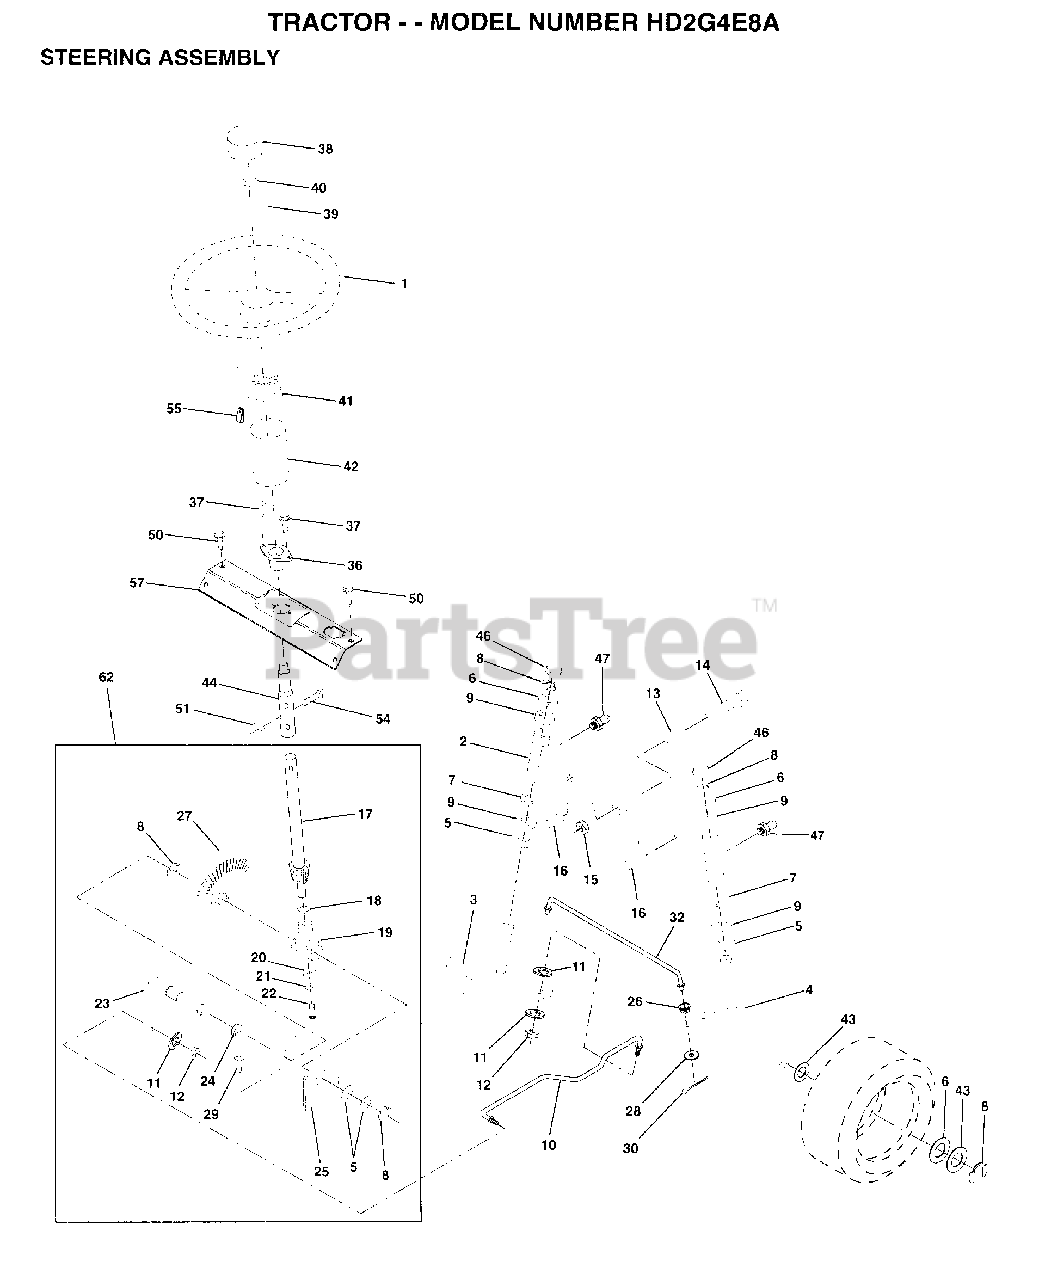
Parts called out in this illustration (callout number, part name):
1	WHEEL STR AYP BLK
2	AXLE ASM FRONT
3	SPINDLE LH
4	SPINDLE RH
5	WASHER .T
6	WASHER
7	WASHER
8	RING
9	COL. SRTG. BEAR.
11	LOCKWASHER
13	BEARING
14	BOLT HEX 5/8-11
15	"NUT-LOC,FLANGE LT"
16	AXLE PIN
17	SHAFT ASM STEERIN
18	THRUST WASHER
19	SUPPORT.SHAFT
21	LOCKWASHER
22	SCREW.SCKTHD.CAP
24	NYLINER T
25	"BRKT,STEERING"
26	BUSHING.DRAGLINK
27	GEAR SECTOR
28	WASHER
29	SCREW
30	COTTER PIN
32	TIE ROD
38	CAP STEER AYP
39	WASHER T
40	GRIPCO NUT
41	ADAPTER-WHEEL LT
42	BOOT SHAFT STEER
43	WASHER
46	CAP
47	ZERK M
50	SCREW HEX CRT
51	NUT
54	BOLT
55	CLIP TINNERMAN
57	SUPPORT SHAFT STR
